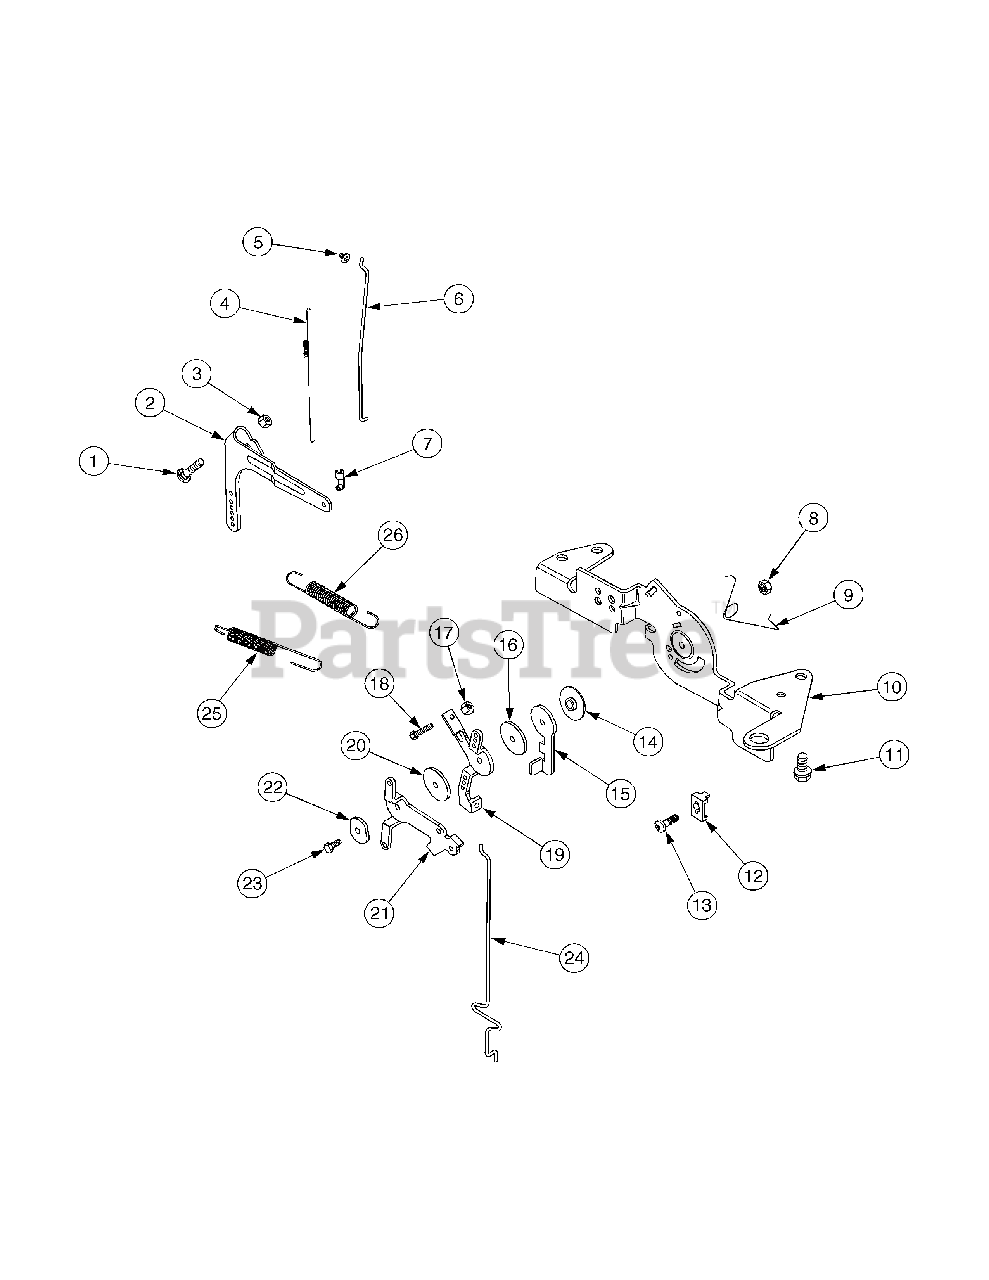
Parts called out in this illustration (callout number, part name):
1	Bolt, Round Hd, M6-1.0 x 25
2	Lever, Governor
3	Nut, Hex Flange, M6-1.0
4	Spring, Linkage
5	Bushing, Linkage Retaining
6	Linkage, Throttle
7	Bushing, Throttle Linkage
8	Nut, Hex Lock
9	Spring, Choke Return
10	Bracket, Control
11	Screw, Hex Flange
12	Clamp, Bowden
13	Screw, Thread Forming
14	Spacer, Control Assembly
15	Lever, Throttle Actuator
16	Washer, Plain
17	Nut, Hex M4 x 0.7
18	Screw, Hex. Hd, M4-0.7 x 25
19	Lever, Throttle Control
20	Washer, Plain
21	Lever, Choke
22	Washer, Wave
23	Screw, Hx Flange, M5-0.8 x 20
24	Linkage, Choke
25	Spring, Governor
26	Spring, Governor
